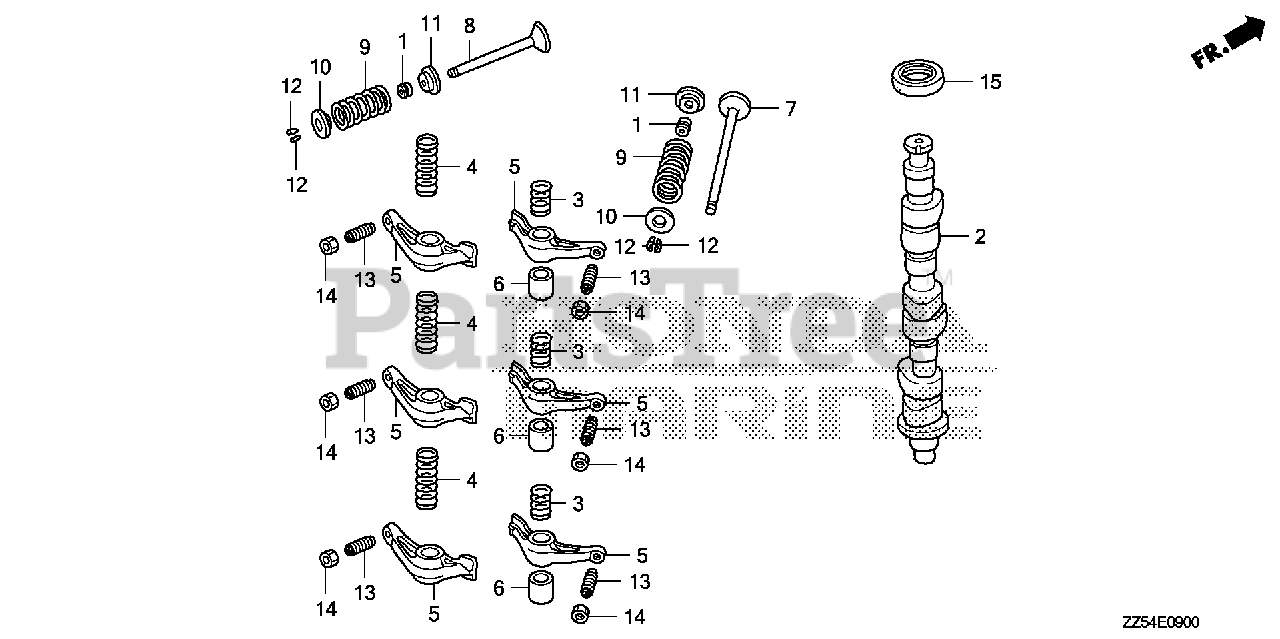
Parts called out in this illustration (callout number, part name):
1	SEAL, VALVE STEM
3	SPRING, ROCKER ARM A
4	SPRING, ROCKER ARM B
5	ARM, IN. ROCKER
6	COLLAR, ROCKER
7	VALVE, IN.
8	VALVE, EX.
9	SPRING, VALVE
10	RETAINER, VALVE SPRING
11	SEAT, VALVE SPRING
12	COTTER, VALVE
13	SCREW, TAPPET ADJUSTING
14	NUT, TAPPET ADJUSTING
15	OIL SEAL (30X42X8)
